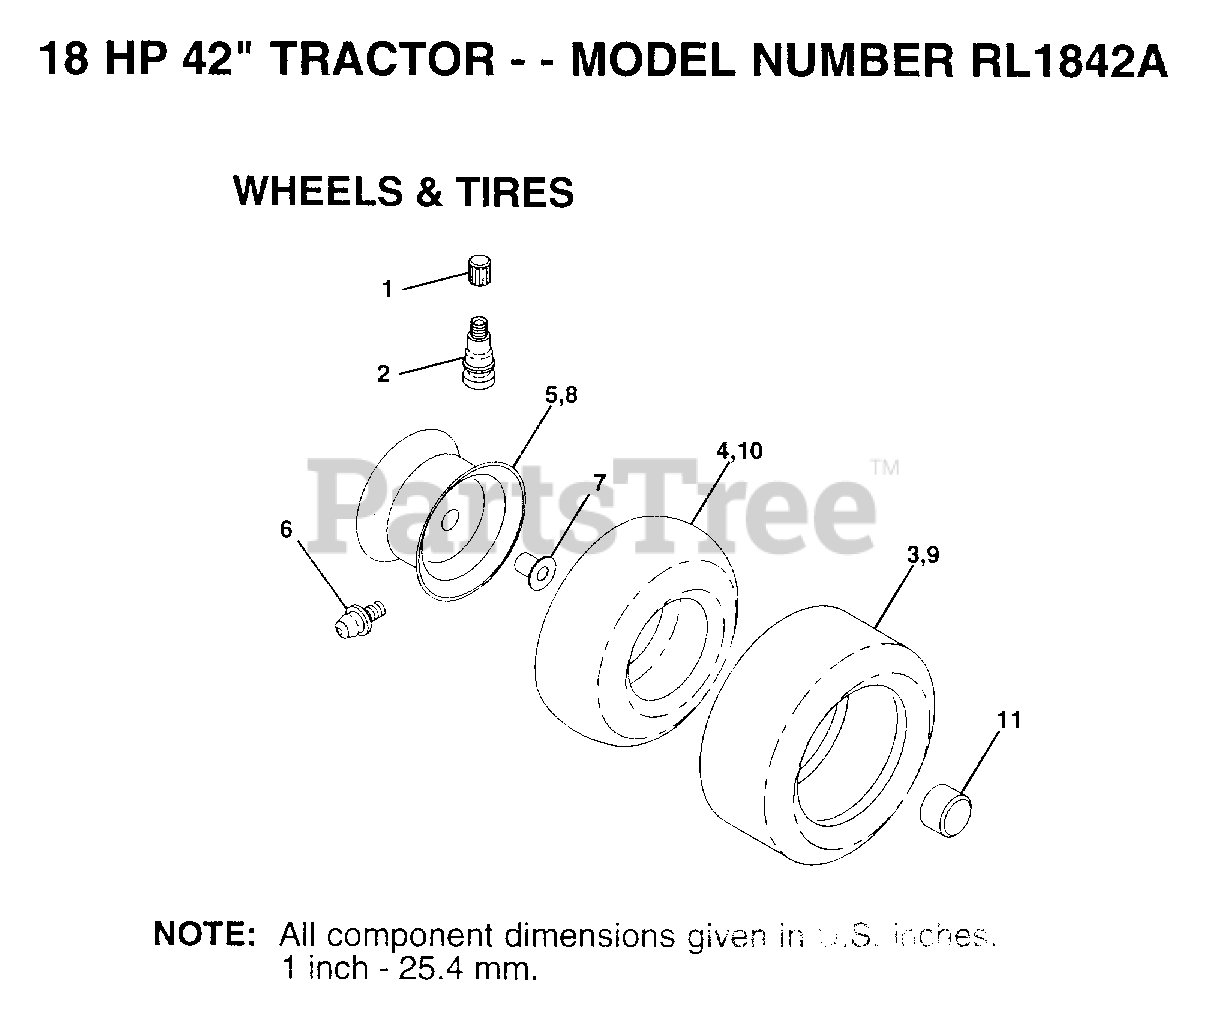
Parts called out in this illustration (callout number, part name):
1	VALVE CAP
2	VALVE STEM LT
4	TUBE.5.3/4.5/6
6	FITTING LT
7	"FLANGE, BEARING"
10	TUBE.18X9.5-8
11	HUB CAP
